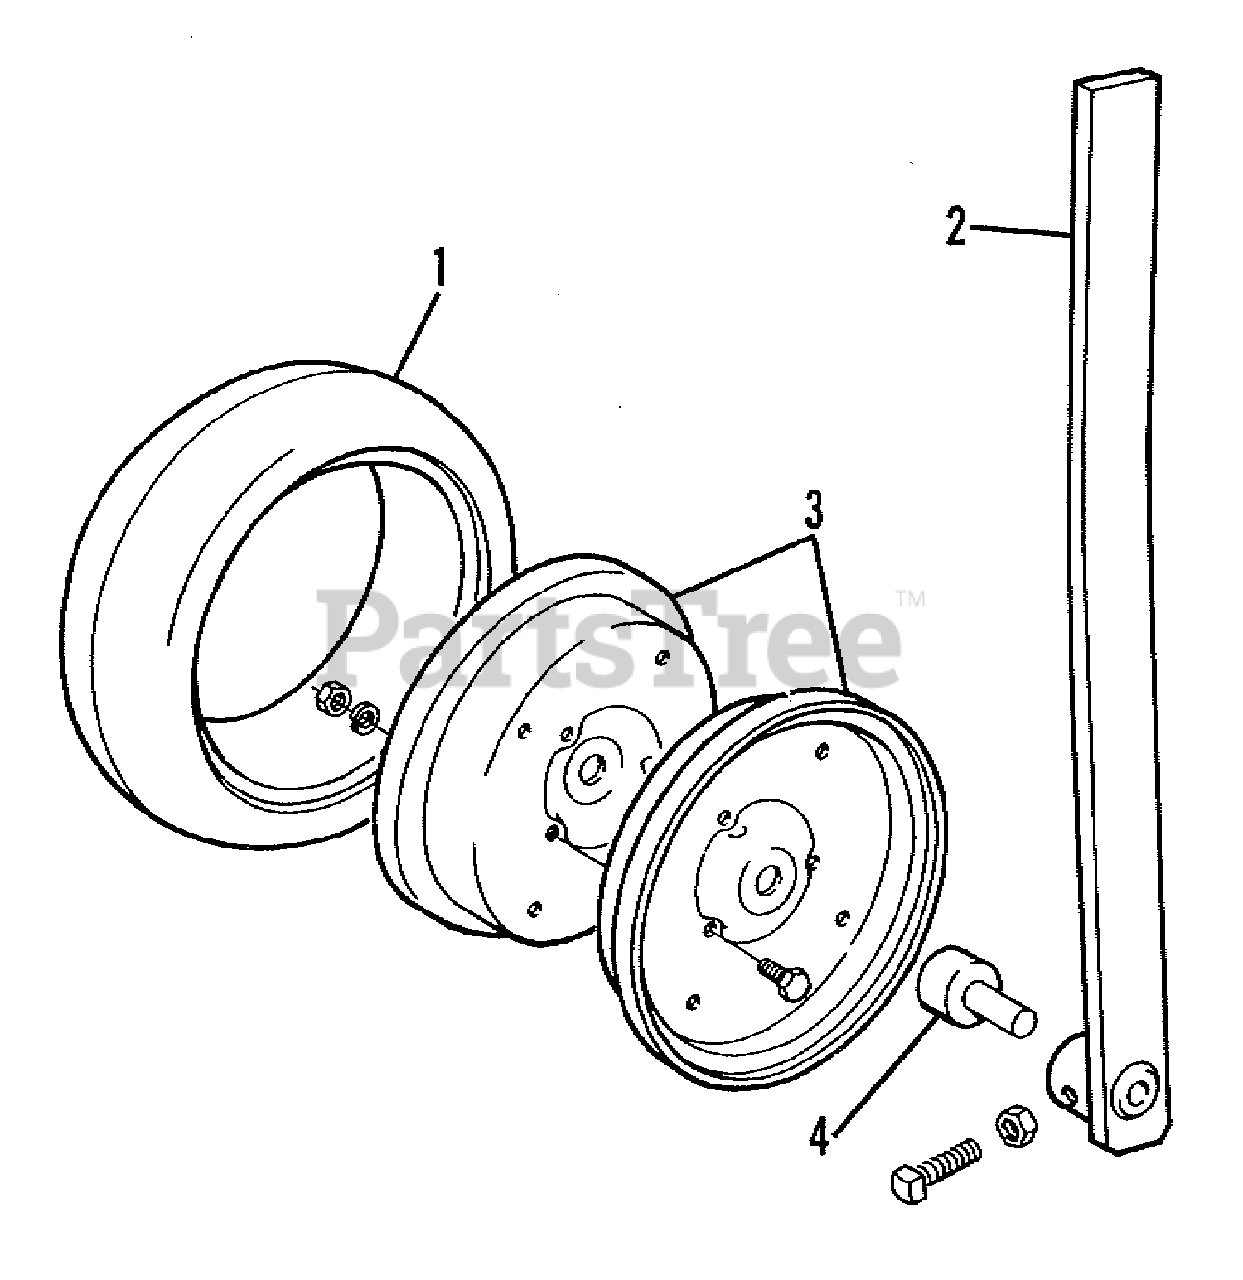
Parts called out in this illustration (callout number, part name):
2	BAR ASSEMBLY, Adjusting
3	CAPSCREW, 5/16NC x 5/8
3	LOCKWASHER, 5/16
3	NUT, 5/16NC
4	SPINDLE, Wheel
